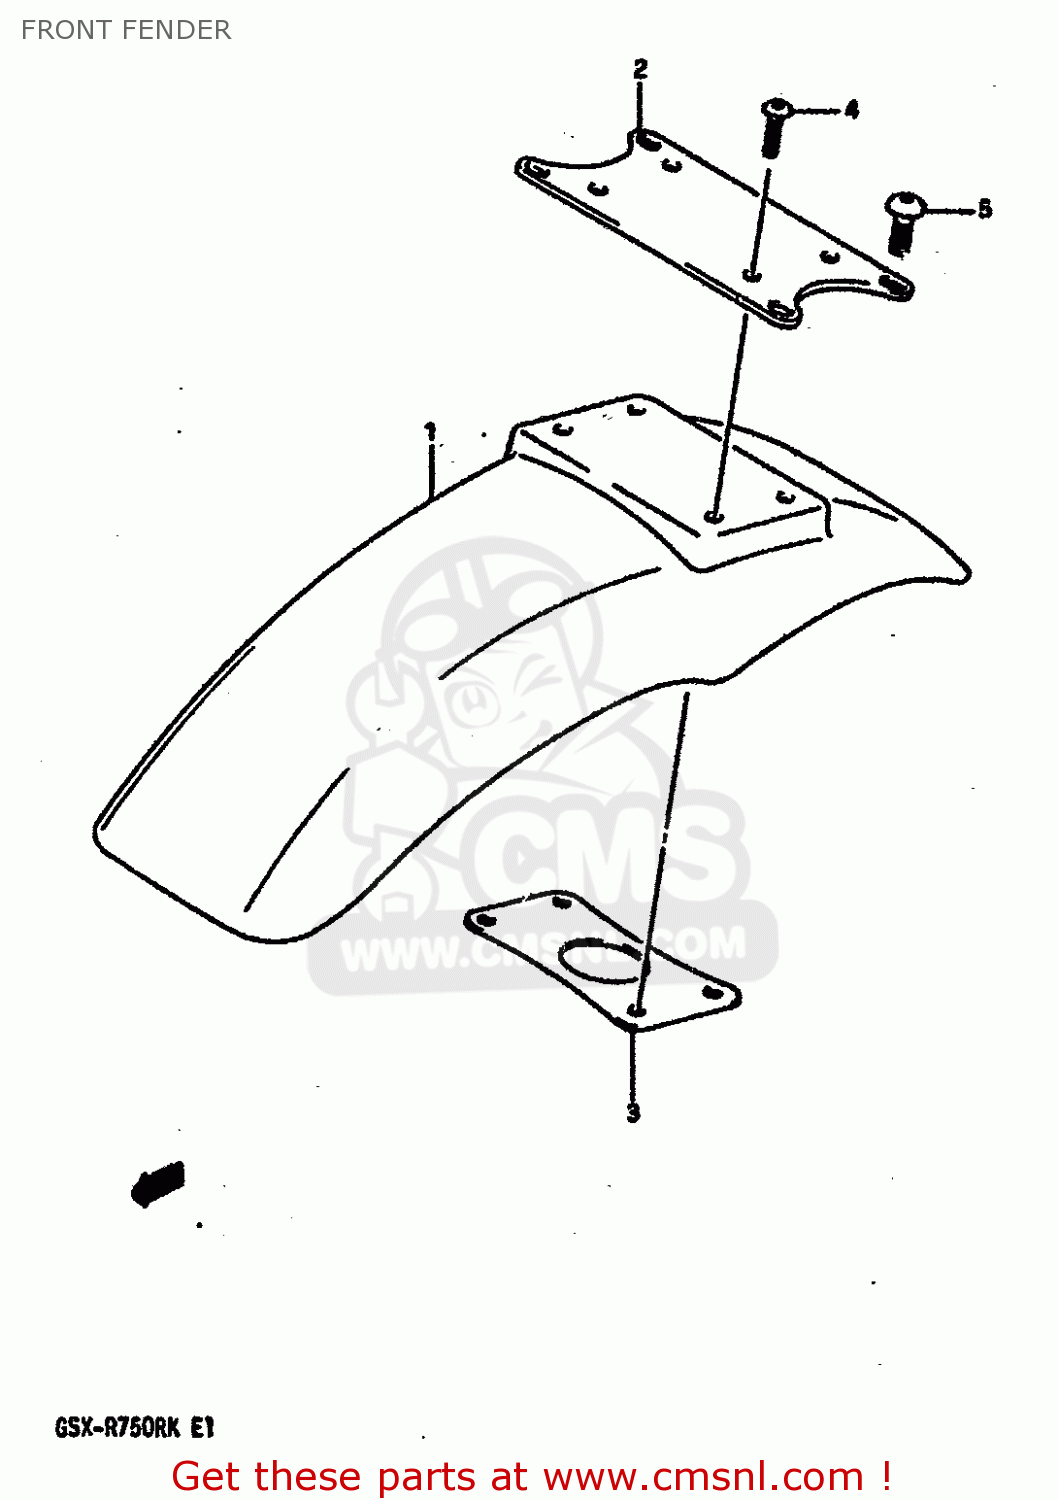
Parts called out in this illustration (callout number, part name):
1	FENDER,FR
2	BRACE,FRONT FENDER
3	BRACE,FR FENDER INNER
4	SCREW(5X18)
5	SCREW(8X16)
